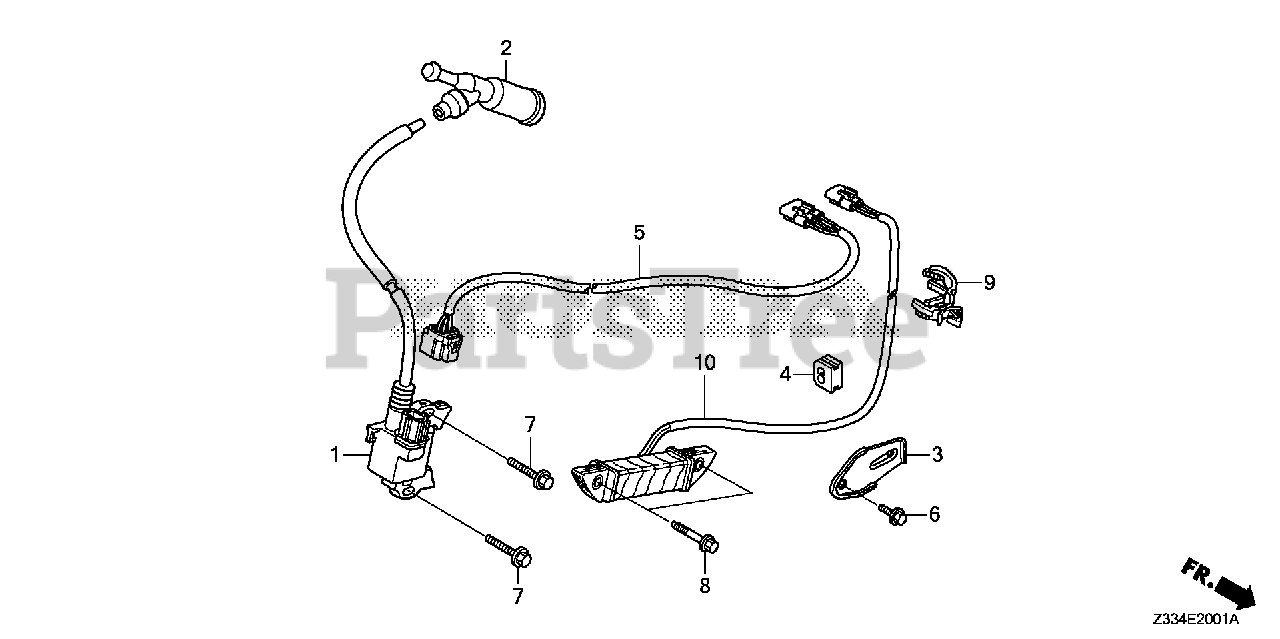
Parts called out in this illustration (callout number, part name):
1	COIL ASSY., IGNITION
2	CAP ASSY., NOISE SUPPRESSOR (NGK Y-EZD)
3	CLAMP, WIRE
4	GROMMET, WIRE
5	WIRE HARNESS ASSY., ENGINE
6	BOLT, FLANGE (6X12) (CT200)
7	BOLT, FLANGE (6X28) (CT200)
8	BOLT, FLANGE (6X25) (CT200)
9	CLIP, HARNESS
10	COIL ASSY., POWER
